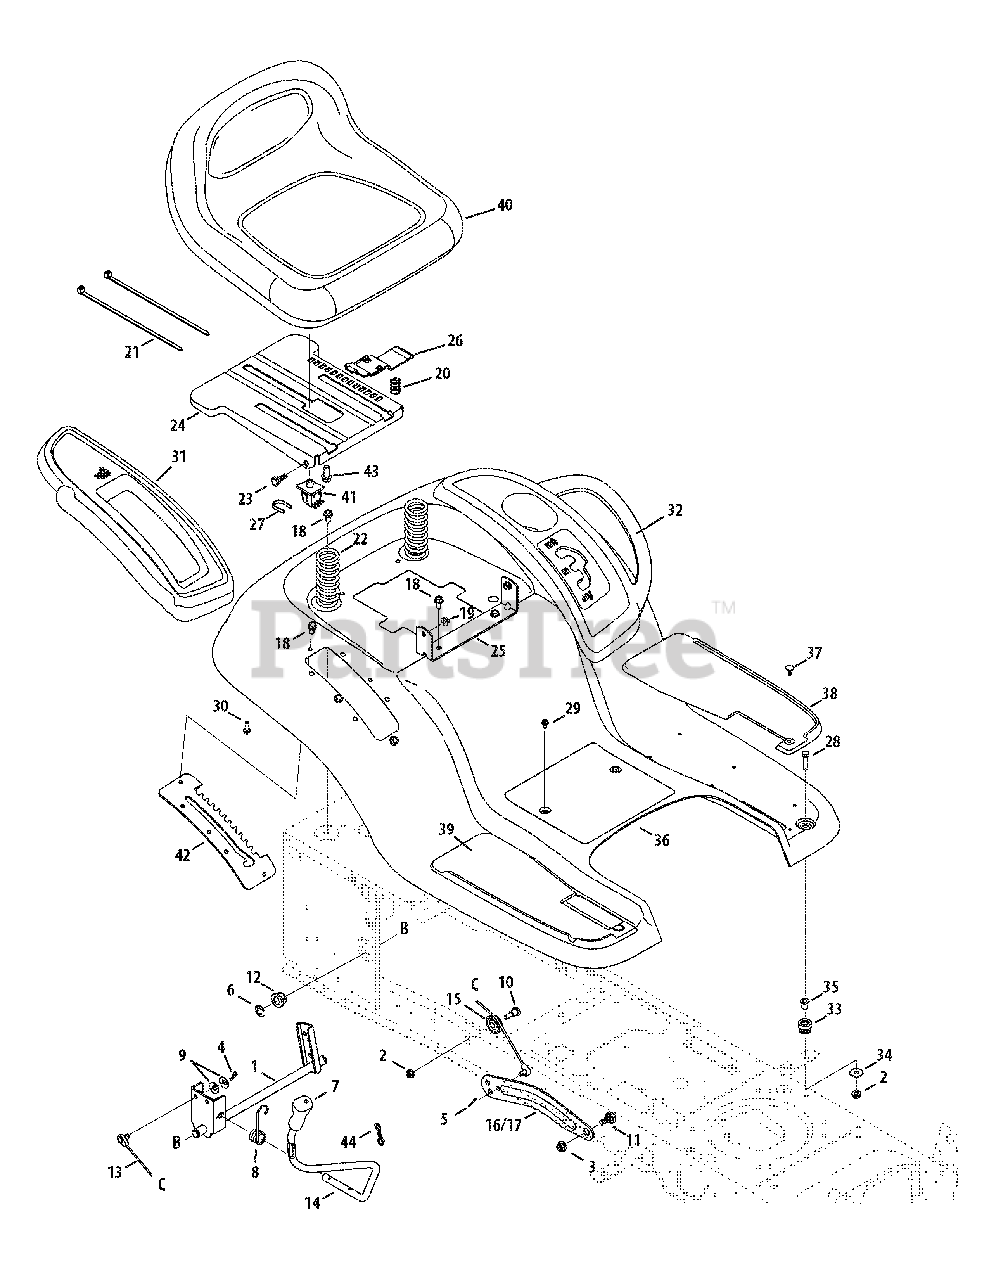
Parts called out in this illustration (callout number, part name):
1	Shaft Ass’y, Lift
2	Nut, Flange Lock, 5/16-18, Grf
3	Nut, Flange Lock, 3/8-16, Grf
4	Pin, Cotter, .072 Dia. x 1.13
5	Pin, Cotter, Bow-Tie 72
6	Ring, E Type, .625 Dia. Shaft
7	Grip, Handle, Cub, .50 ID
8	Spring, Torsion
9	Washer, Spring, .401 x .870 x .063
10	Screw, Shoulder, .437 x .470, 5/16
11	Bolt, Shoulder, .625, 3/8-16
12	Bearing, Hex Flange
13	Cable, Lift, 16.16
14	Handle, Lift,
15	Pulley, Roller, Cable
16	Arm, Lift, 42" Rt RH
17	Arm, Lift, 42" Rt LH
18	Screw, Self-tapping, 5/16-18, .750,
19	Nut, Flange Lock, 5/16-18, Gr5, Sd
20	Spring, Comp, .68 x 1.065 x .055
21	Cable, Tie, 3/16 x .05 x 7.4
22	Spring, Comprs, 1.71 x 3.735 x .238
23	Screw, Shoulder, .437 x .268, 5/16-18
24	Bracket, Mounting, Seat
25	Bracket, Pivot, Seat
26	Lever, Seat Adjustment
27	Clip, Retaining, Switch
28	Hex Screw, 5/16-18, 1.25, Gr5, Std
29	Screw, Self-tapping, 1/4-20, 0.500
30	Screw, HL, 1/4-15, 0.750,
31	Cover, Fender, RH
32	Cover, Fender, LH
33	Grommet, .4375 ID x .750
34	Washer, Flat .344 x 1.00 x .063
35	Spacer, Flange, .3125 x .4375 x .625
37	Clip, Ratchet, .250 Dia
38	Pad, Foot, LH
39	Pad, Foot, RH
40	Seat, Medium Back Cloth, Cub
41	Switch, Seat
42	Bracket, Lift, Man PTO, 10 Pos
43	Hex Flange Screw, 3/8/16, .875, Gr5
44	Pin, Cotter, Bow-Tie 72
